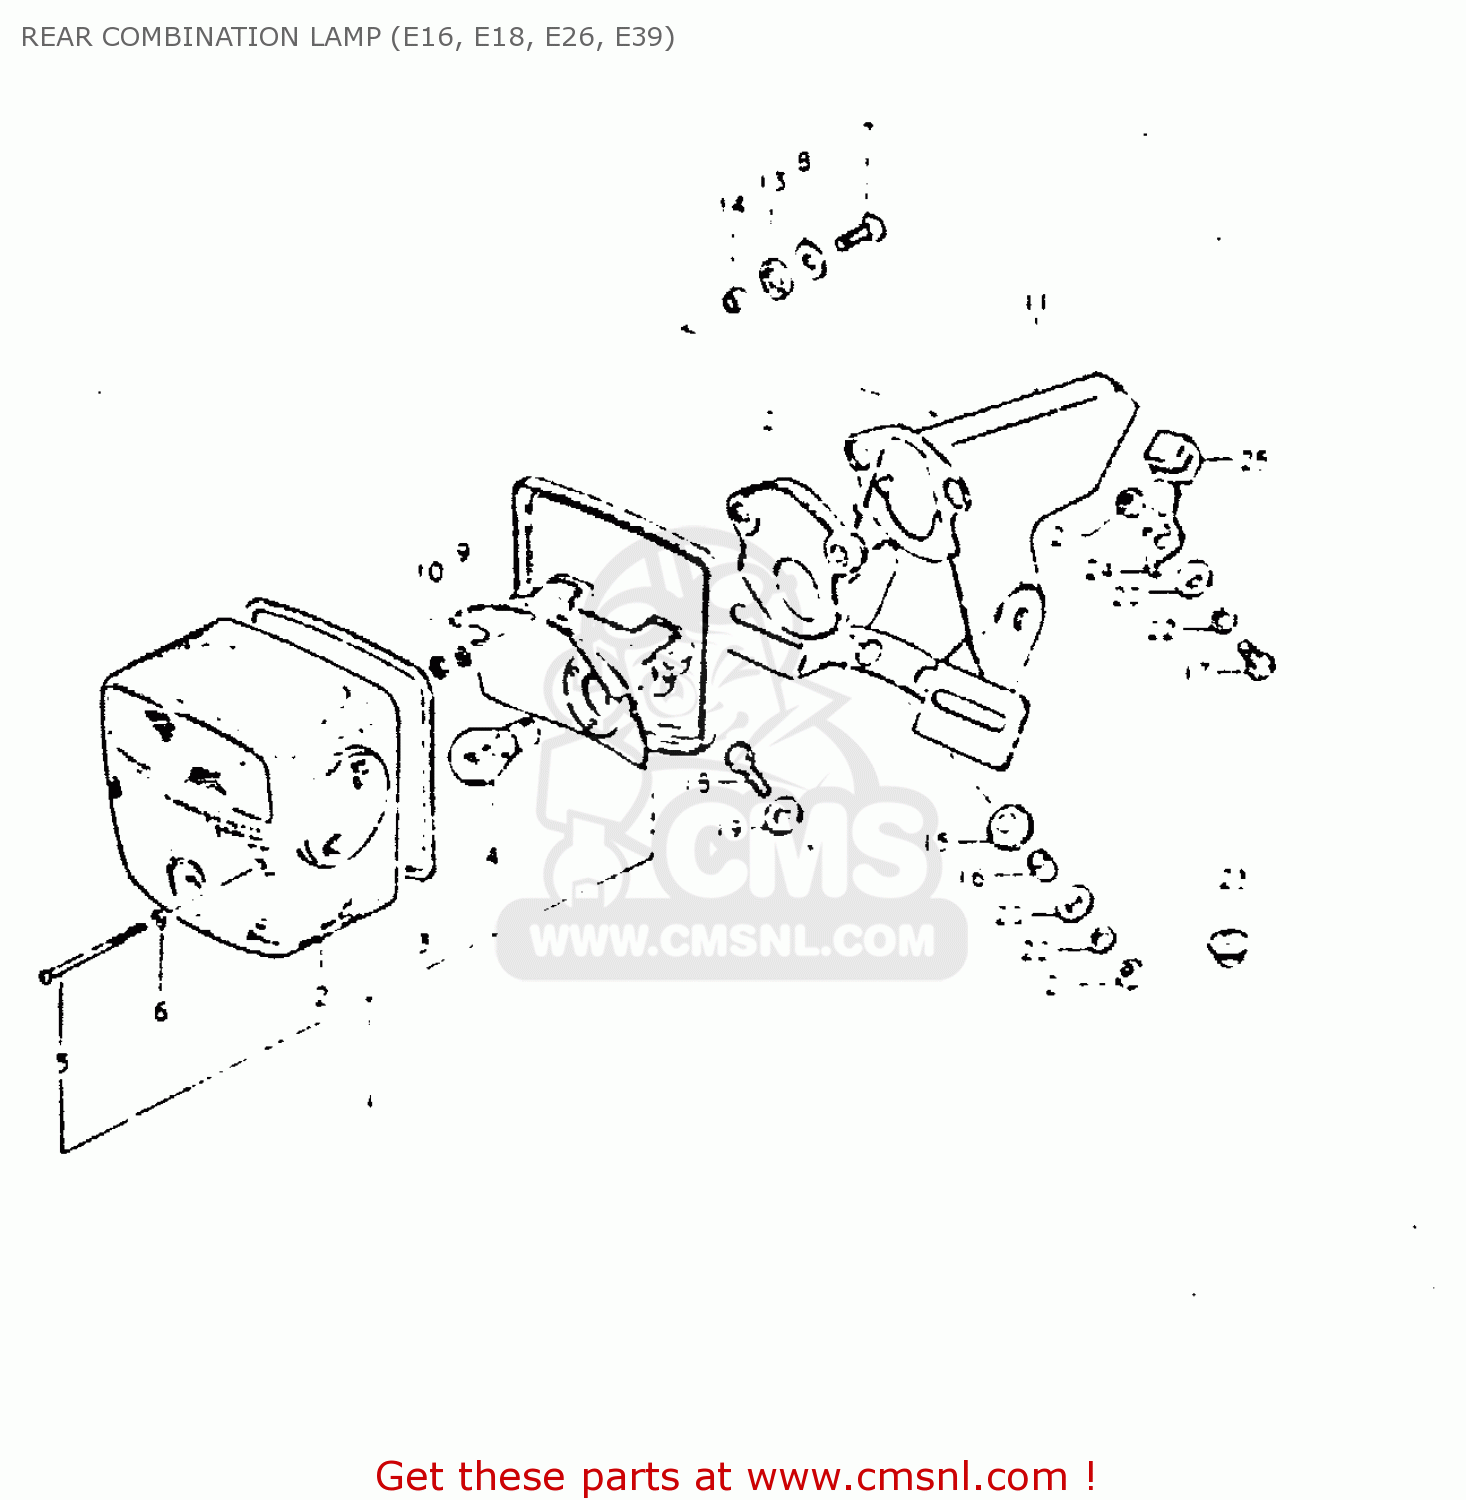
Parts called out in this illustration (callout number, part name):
1	LAMP UNIT, TAIL
2	LENS
3	GASKET (NAS)
4	BULB (6V,21/5W)
5	SCREW (4X55)
6	GASKET (NAS)
7	SCREW
8	WASHER,REAR COMBINATION LAMP
9	NUT
10	LOCK WASHER
11	BRACKET SET
12	CUSHION
13	CUSHION
14	SPACER,REAR COMBINATION LAMP
15	CUSHION,REAR COMBINATION LAMP
16	SPACER
17	BOLT
18	BOLT (8X30)
19	WASHER (6.5X20X1.2)
20	WASHER
21	NUT
22	WASHER
23	GROMMET
24	PLATE
25	CUSHION
